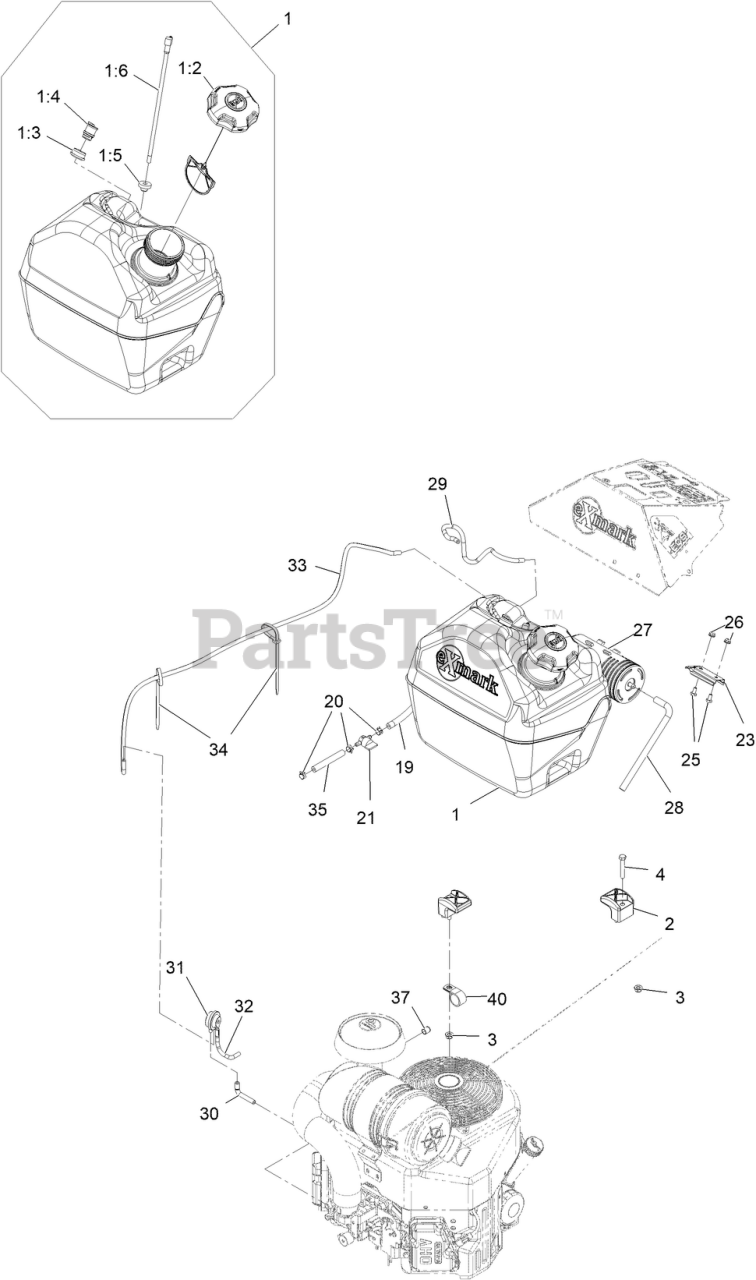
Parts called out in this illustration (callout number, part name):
1	Fuel Tank ASM, 5 Gal
1:2	CAP-FUEL, RATCHETING
1:3	GROMMET
1:4	VALVE-VENT, FUEL
1:5	BUSHING
1:6	FITTING, FUEL W/LINE AND SCREEN
3	NUT-HF, NI
4	SCREW-HH
19	HOSE-FUEL
20	CLAMP-HOSE
21	VALVE-FUEL
23	BRACKET-CANISTER, CARBON
25	SCREW-HH
27	CANISTER-CARBON, 800CC
28	HOSE-VENT, CANISTER
29	HOSE-EMISSIONS
30	HOSE-VENT, FORMED
31	VALVE-CONTROL, VACUUM
32	HOSE-VENT, FORMED
33	HOSE-VENT, FORMED
34	TIE-CABLE
35	HOSE-FUEL
37	PLUG-PORT
40	CLIP-LOOM
